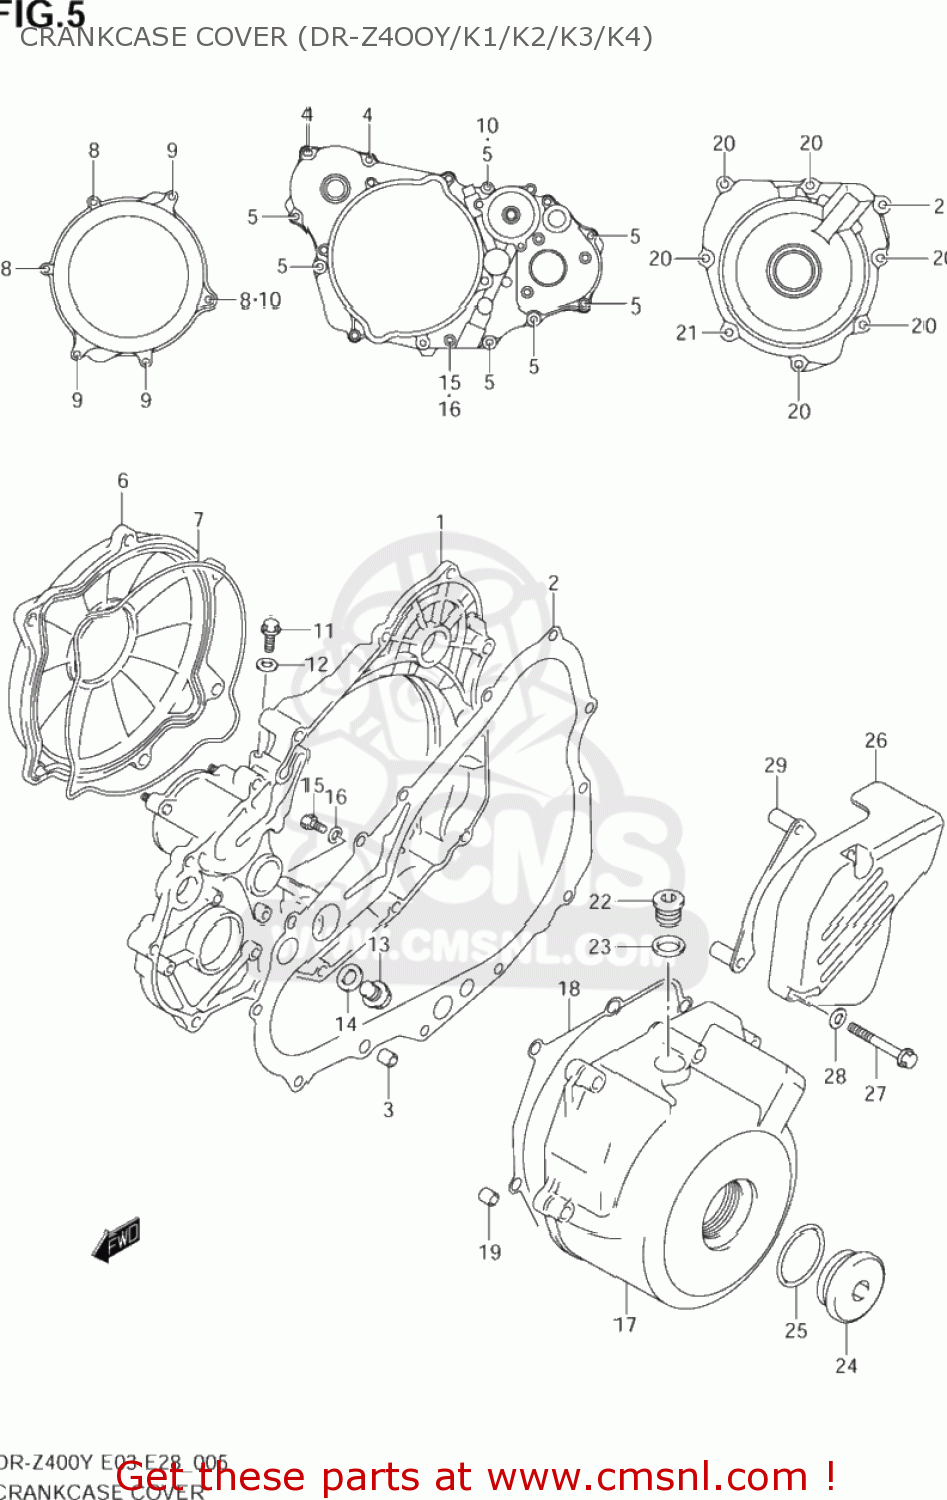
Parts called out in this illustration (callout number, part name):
1	COVER,CLUTCH INNER
2	GASKET,CLUTCH COVER (NAS)
3	PIN
4	SCREW
5	BOLT,G/S SWITC
6	COVER,CLUTCH OUTER
7	O RING,CLUTCH COVER OUTER
8	SCREW
9	BOLT
10	GASKET(5.8X13X1.2) (NAS)
11	BOLT
12	GASKET(5.8X13X1.2) (NAS)
13	PLUG(12X10)
14	GASKET(12.1X16.2X3.7) (NAS)
15	BOLT
16	GASKET(6.2X11X1).2 (NAS)
17	COVER,MAGNETO
18	GASKET,MAGNETO COVER (NAS)
19	PIN
20	BOLT,G/S SWITC
21	BOLT
22	PLUG
23	GASKET(13.8X18.8X4.8) (NAS)
24	PLUG
25	O RING(D:3.1,ID:32.7)
26	COVER,ENGINE SPROCKET
27	BOLT
28	WASHER(6.5X14X2)
29	PLATE,FR CHAIN GUIDE
